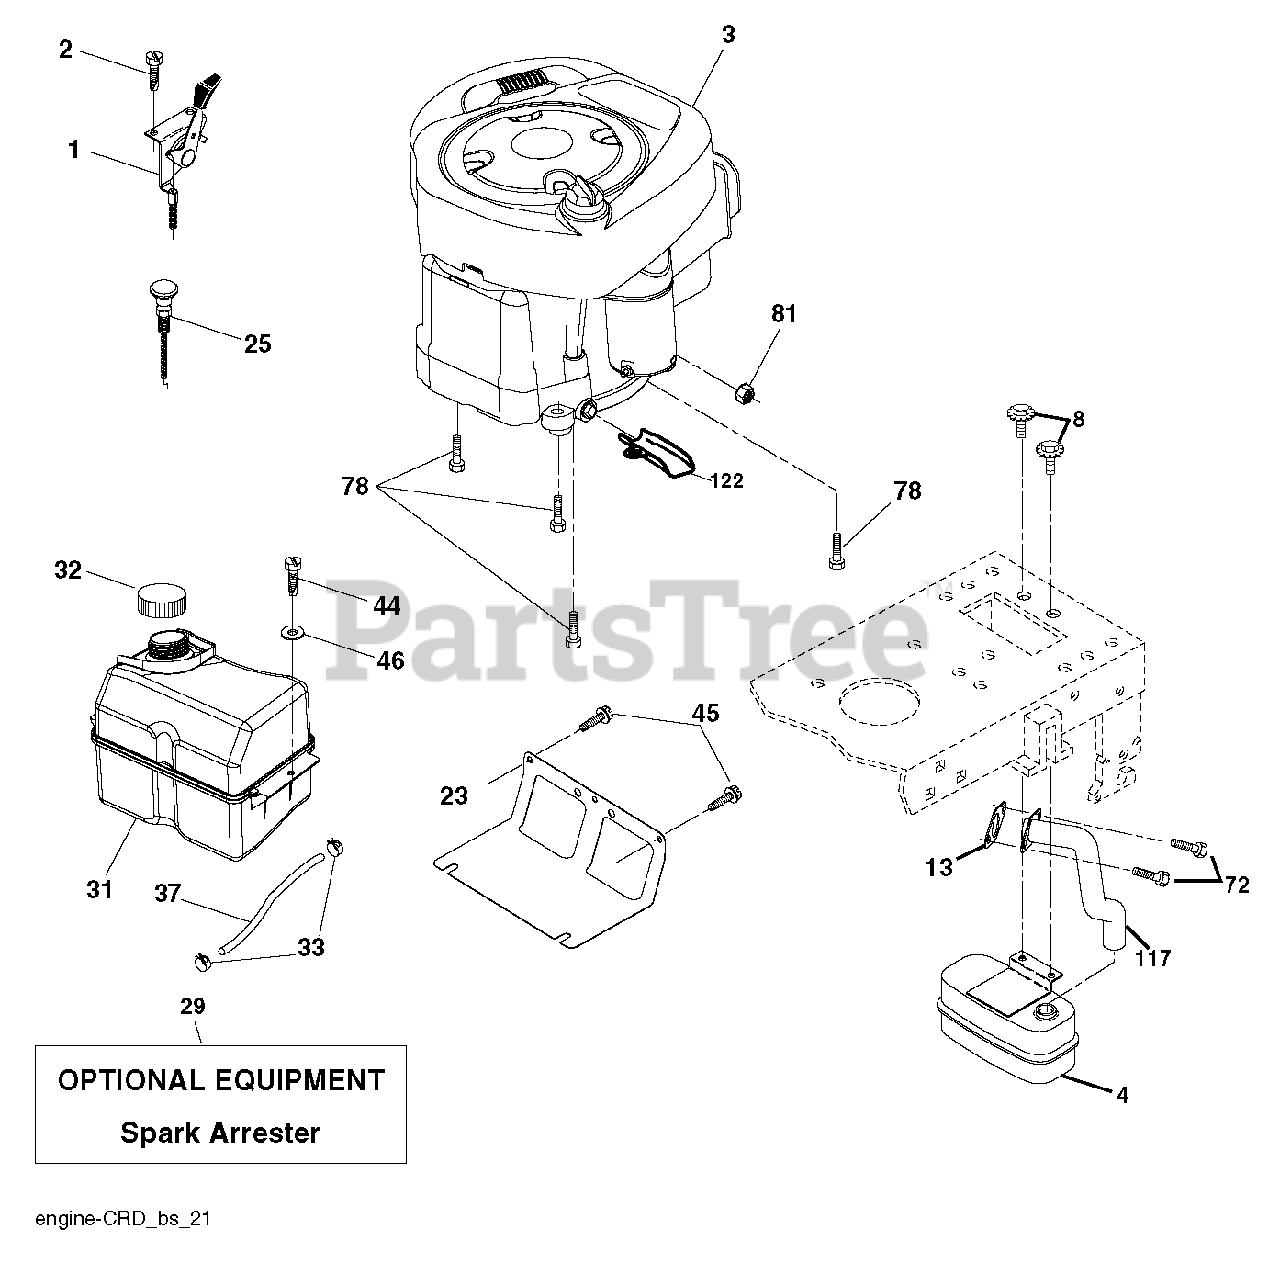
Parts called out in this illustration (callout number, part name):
1	CONTROL TH/CH FLAG
2	SCREW
4	MUFFLER.SINGLE.CYL.KOHL/B&S
8	BOLT, 5/16-18 X 1 3/4
13	REPL BY 532 27 22-93
23	SHEILD.BROWNING.DBR.GUARD
29	ARRESTER SPARK (OPTIONAL)
32	CAP ASM.FUEL.2.25"FR.
33	HOSE CLAMP
37	LINE.FUEL.20
44	SCREW HEXWSHR 1/4-20X3/4
45	SCREW, 3/8-16X3/4
72	SCREW.SOCKET HD.5/16-1
78	SCREW.3/8-16
81	NUT
117	EXHAUST.TUBE.B&S.
122	EXTENSION DRAIN OIL
